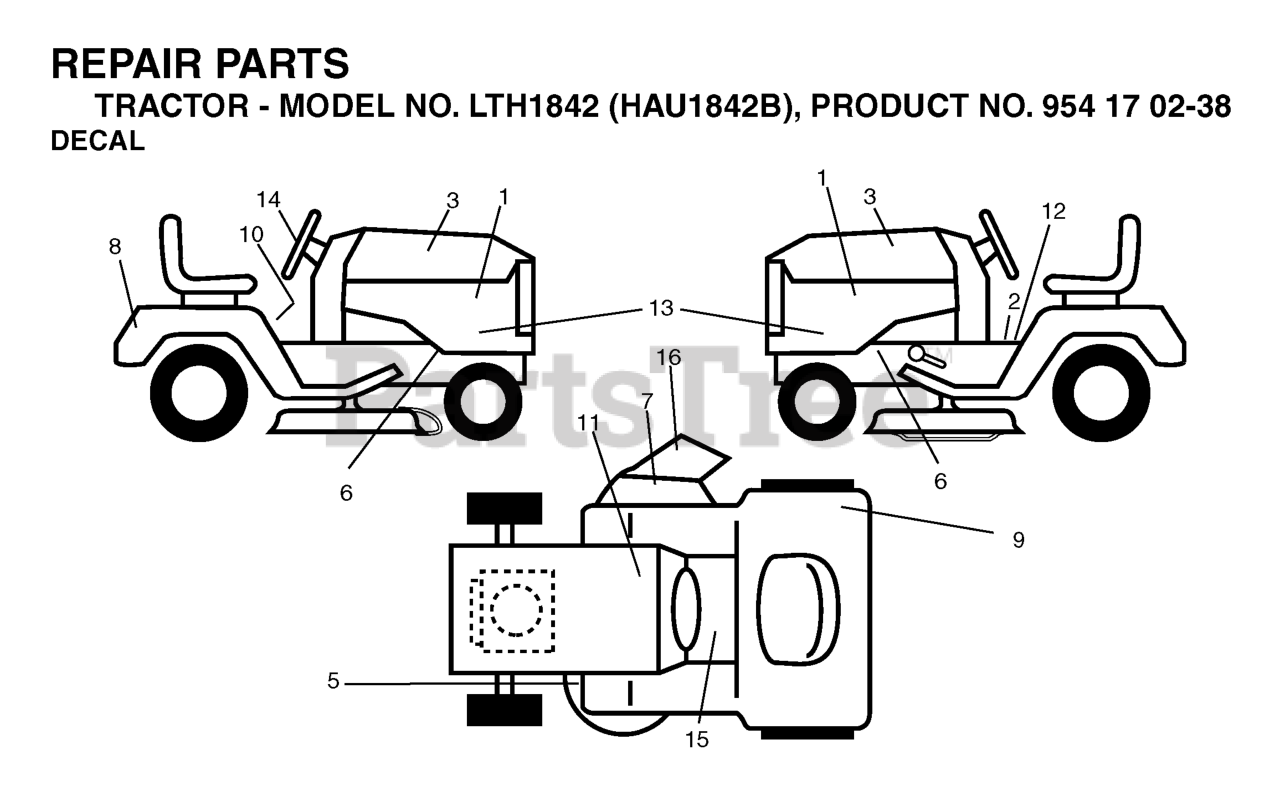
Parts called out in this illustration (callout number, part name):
2	DECAL PARK BRAKE
3	DECAL.HOOD.HUSQVARNA.INTERNATI
5	DECAL V BELT SCHEMATIC
7	DECAL.INTERNATIONL.CUTFINGER
9	DECAL
10	DECAL READ OWNER'S MAN SYMS
11	DECAL BTRY SYMBOLS
12	DECAL
14	DECAL.STEERING.HUSQ.BLUE
15	DECAL
16	DECAL DECK "B" 42"
